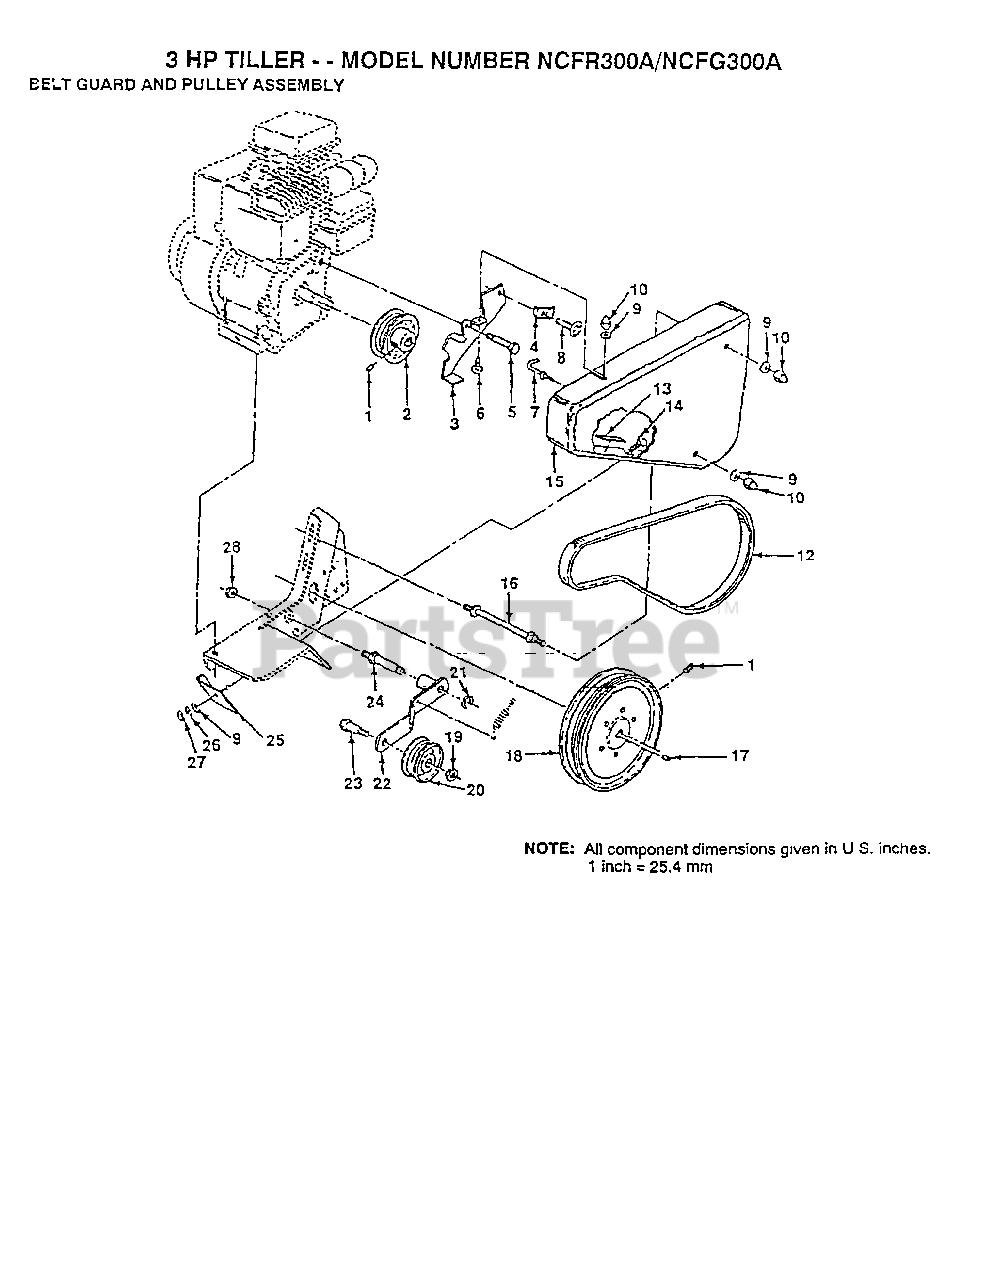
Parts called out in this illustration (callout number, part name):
1	SET SCREW
4	CONDIUT CLIP T
6	BOLT
9	WASHER
10	NUT-CAP TI
13	PAD IDLER TI
14	BOLT T
16	BOLT TI
17	KEY T
18	TRANS SHEAVE RT
19	NUT
21	KLIP RING TI
22	IDLER ARM TI
24	SHAFT IDLER TI
25	SHIELD-DIRT TI
26	LOCKWASHER
28	JAM NUT TI
